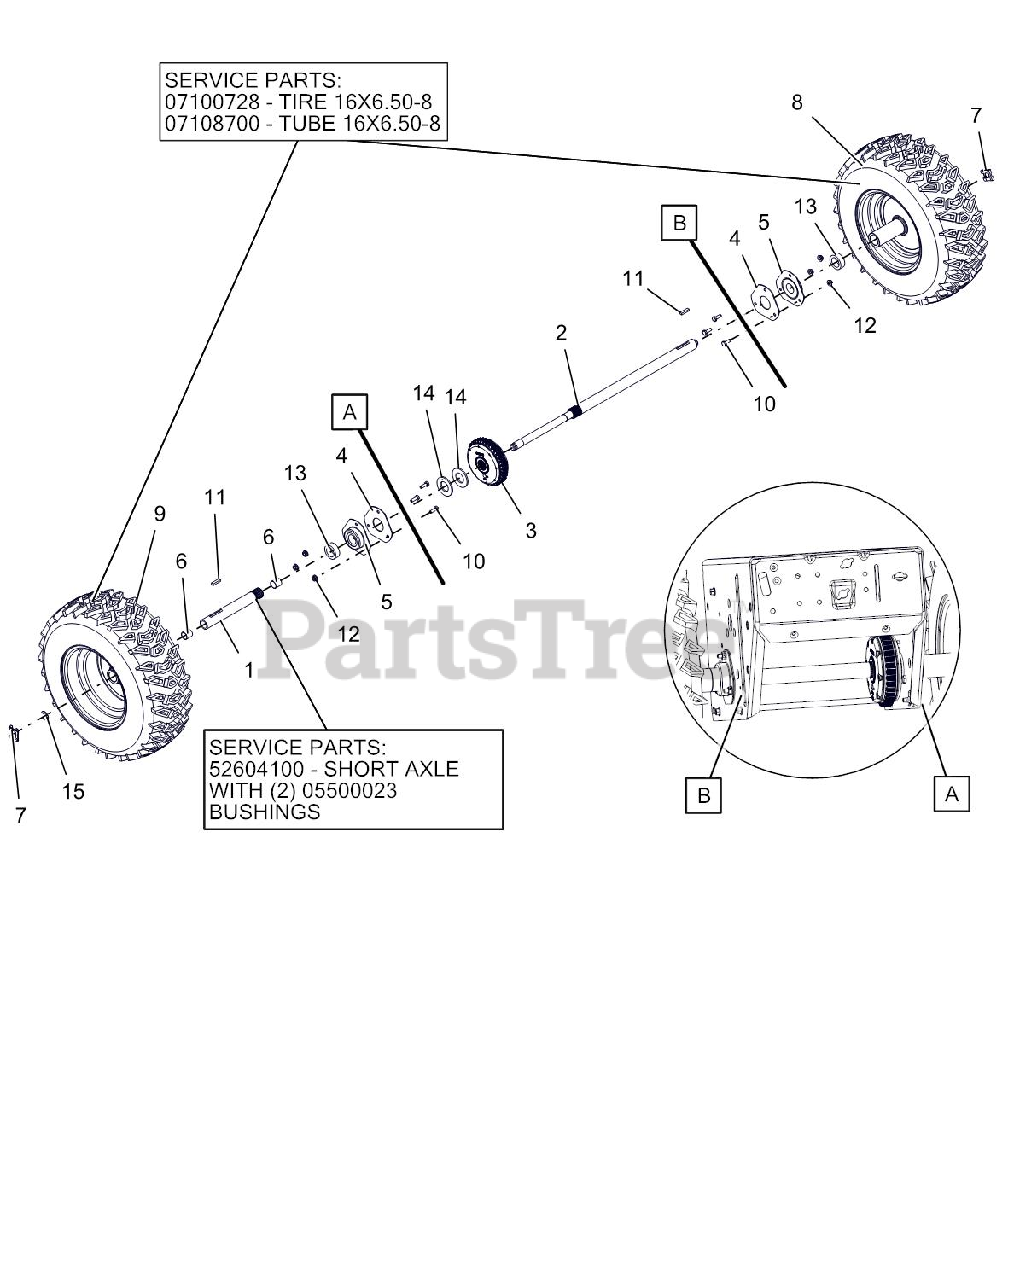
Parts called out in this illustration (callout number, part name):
1	BSHG-SLV .706X.764X.75 BRZ
1	AXLE, SHORT-PRO AUTO DIFF
1	AXLE, SHORT-AUTO W/BUSHINGS
2	AXLE, LONG-PRO AUTO DIFF
3	DIFFERENTIAL, AUTOMATIC
4	PLATE, BEARING SPACER
5	BRG-FLG 1.003/1.000 3 BOLT
6	BSHG-SLV .706X.764X.75 BRZ
7	CLIP, SNAP .625 DIA
8	TIRE/WHEEL,LH 16X6.5-8 DIFF T2
9	TIRE/WHEEL,RH 16X6.5-8 DIFF T2
10	@BLT-HEX .25-20X.75 GR5 YWZC
11	KEY-RECT .25X.188X1.00
12	@NUT-LK-CTR-FLG .25-20 YWZC
13	SPACER, PRO AXLE BEARING
14	WSHR-FL-STL- 1.062X2.0X.134 YZ
15	RG-RTNG-EXT .625X.042
16	TIRE, 16X6.50-8 K478
17	TUBE
